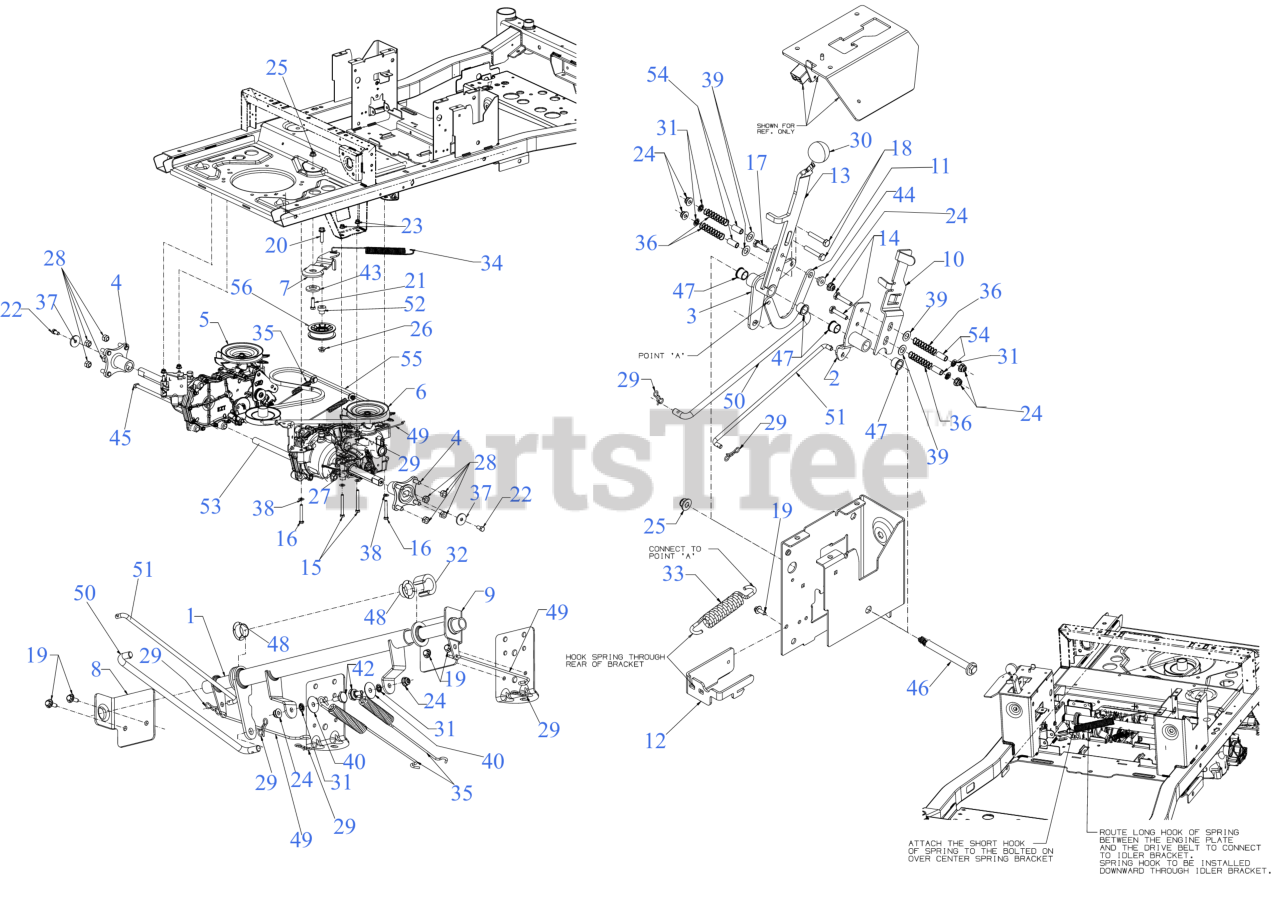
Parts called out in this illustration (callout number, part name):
1	BRAKE PIVOT SHAFT
2	BYPASS LEVER PIVOT ARM
3	PARK BRAKE PIVOT ARM
4	WHEEL HUB ASSEMBLY
4	STUD 7/16-14 x 1.6
5	TRANSMISSION (LH)
6	TRANSMISSION (RH)
7	HYDRO DRIVE IDLER BRACKET
8	BRAKE SHAFT SUPPORT (RH)
9	BRAKE SHAFT SUPPORT (LH)
10	TRANSMISSION BYPASS LEVER
11	OVER CENTER LINK
12	SPRING MOUNTING BRACKET
13	PARK BRAKE LEVER
14	HEX SCREW 1/4-20 x 1.25
15	HEX SCREW 5/16-18 x 2.75
16	HEX SCREW 5/16-18 x 2.25 GR5
17	SCREW 1/4-20 X1.00 GR5
18	SCREW 1/4-20 x 1.50 GR.5
19	SCREW M6-1 x .625
20	HEX HEAD BOLT (3/8-16:1.50 GR8)
21	SCREW 3/8-16 x 1.25 GR5
22	SCREW 3/8-16 x .75 GR 5
23	FLANGE LOCK NUT 5/16-18
24	FLANGE LOCK NUT
26	FLANGE LOCK NUT
27	FLANGE LOCK NUT
28	LUG NUT 7/16-14
29	BOW TIE COTTER PIN 1/4-5/16
30	PARK BRAKE BALL KNOB
31	RETAINER-BOLT .25ID x .50OD
32	SPACER: .76ID x .75
33	EXTENSION SPRING .57 x 5.38
34	EXTENSION SPRING .75 DIA X 10.27
35	EXTENSION SPRING .60 DIAx8.69
36	COMPRESSION SPRING
37	FLAT WASHER .390x1.500x.134
38	FLAT WASHER
39	WASHER THRUST .375X.70X.030
40	FLAT WASHER
42	SHOULDER SCREW
43	SHOULDER SPACER
44	SHOULDER SPACER
45	SUPPORT TUBE ROD
46	SHOULDER SCREW .491x3.937 3/8-16
47	FLANGE BUSHING
48	FLANGE BEARING .75 x 1.125 x .375
49	HYDRO BYPASS ROD
50	BRAKE LINK
51	BYPASS LINK
52	SHOULDER SPACER
53	SUPPORT TUBE
54	SPACER .252x.350x.760
55	TRANSMISSION DRIVE BELT A x 67
55	Cub Cadet TRANS DRIVE BELT A x 67 RZT
55	Troy-Bilt TRANSMISSION DRIVE BELT
56	FLAT IDLER PULLEY 3.00 OD
